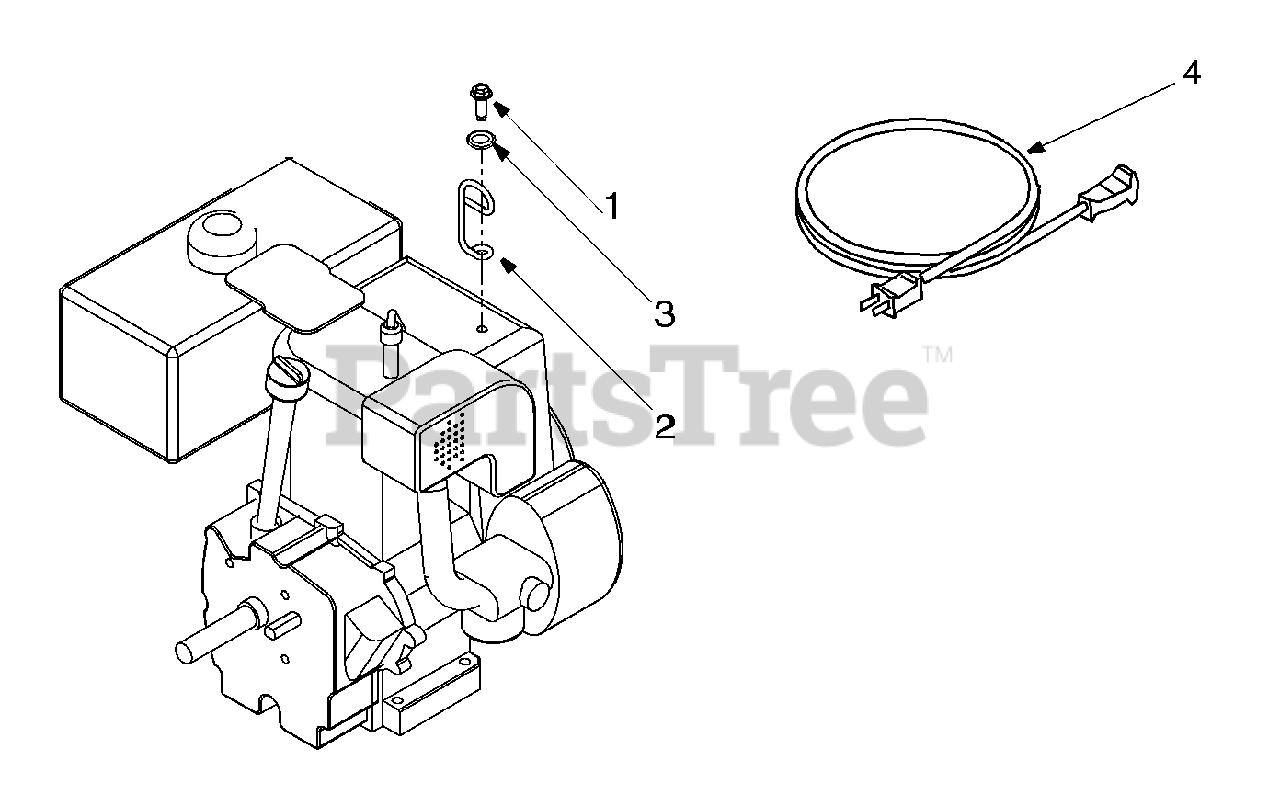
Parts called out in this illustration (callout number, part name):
1	Hex Lock Nut: 1/4-20
2	Cable Guide
3	Flat Washer
4	Extension Cord: 110V, 3-prong
